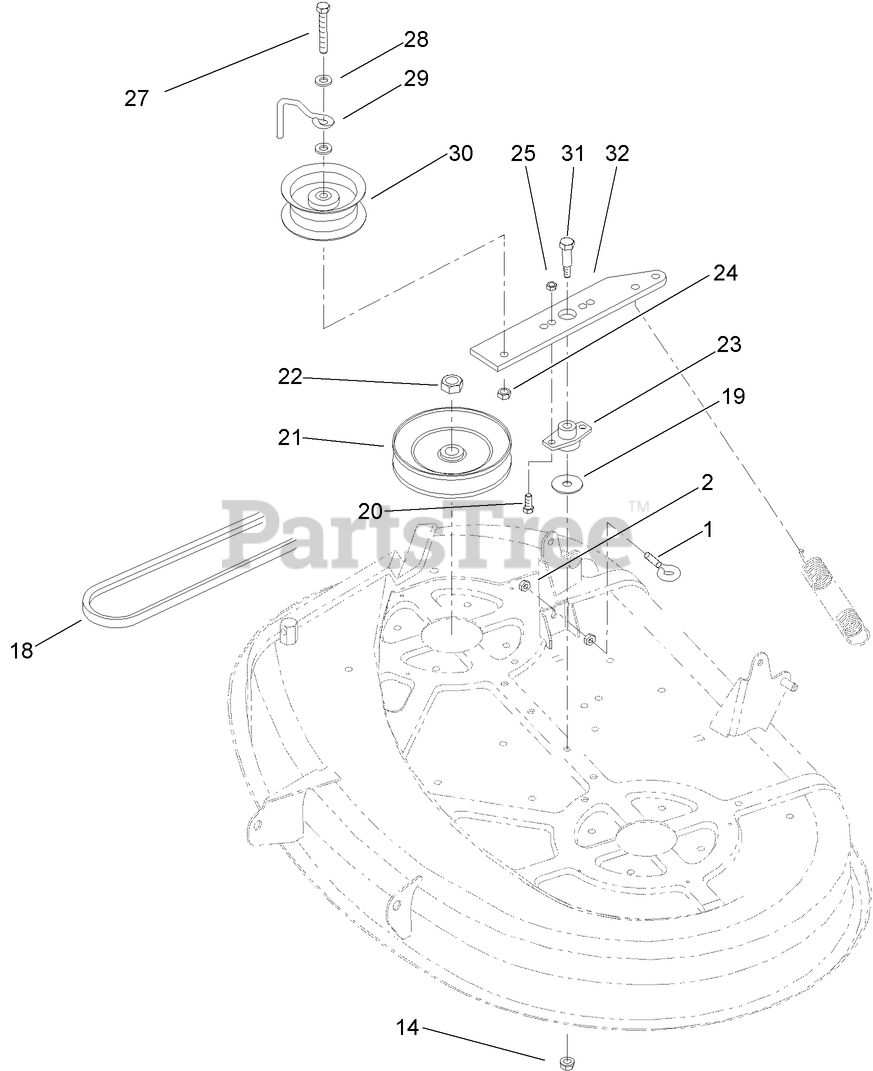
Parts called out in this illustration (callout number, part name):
1	EYEBOLT
2	NUT-JAM
14	NUT-LOCK, NI
18	V-BELT
19	WASHER-FLAT
20	SCREW-HH
21	PULLEY
22	NUT-HEX
23	BUSHING-ARM, IDLER
24	NUT-LOCK, NI
25	NUT-LOCK, NI
27	SCREW-HH
28	WASHER-FLAT
29	GUIDE-IDLER, BELT
31	SCREW-SHOULDER, HH
32	ARM-IDLER
